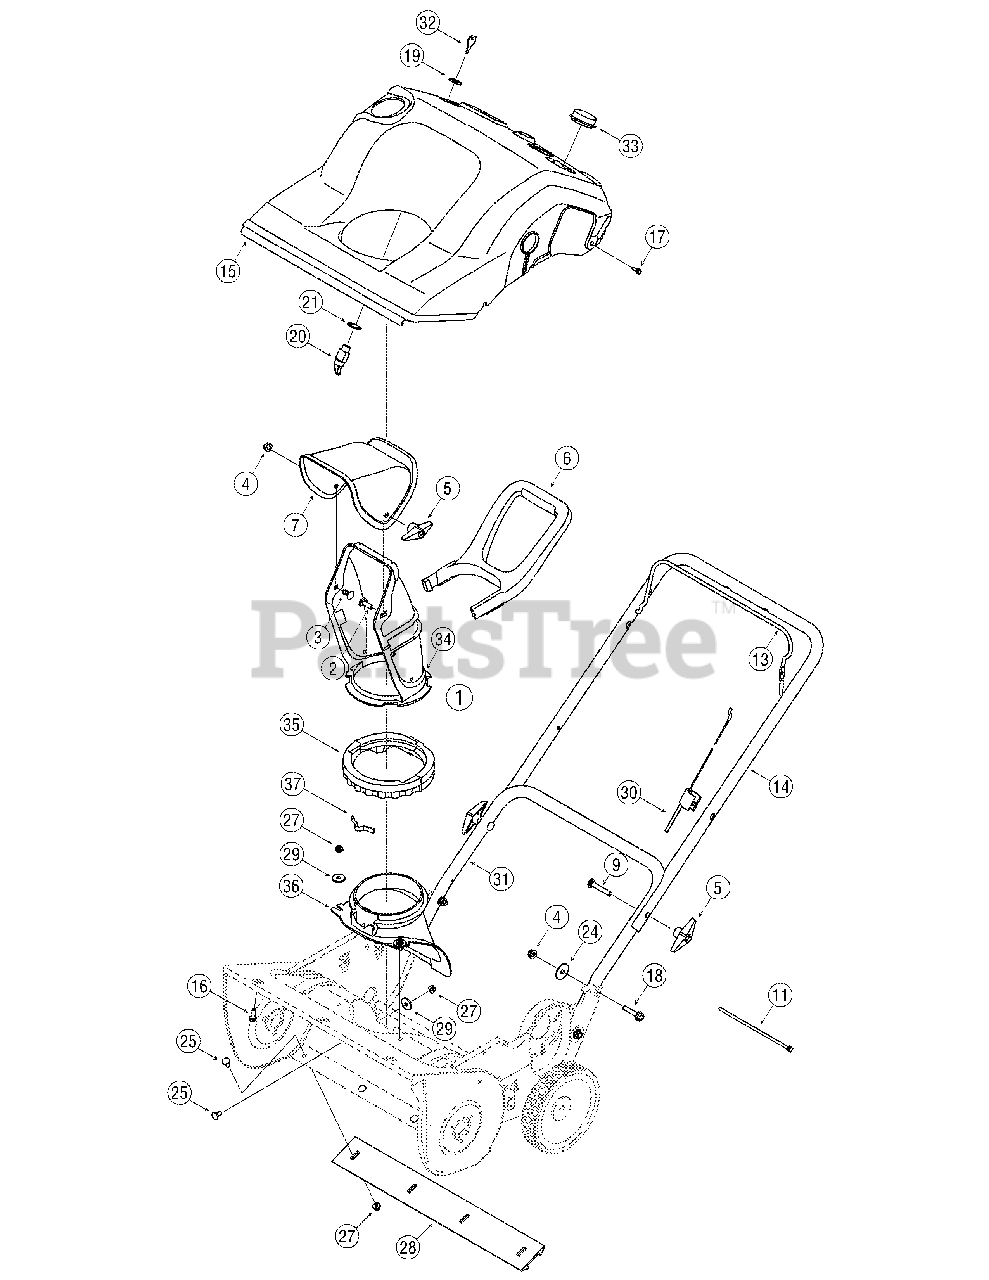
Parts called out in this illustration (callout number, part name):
1	Lower Chute Ass’y (Incl. #5-7 and 10)
2	Carriage Screw 5/16-18 x 1.0
3	Carriage Bolt 5/16-18 x .75
4	Flange Locknut 5/16-18 Gr. F, Nylon
5	Handle Knob Assembly
6	Chute Handle
7	Upper Chute
8	Flat Washer .349 ID x .879 OD x .063
9	Carriage Bolt 5/16-18 x 2.0 Gr. 5
11	Cable Tie
15	Shroud Ass’y (98 cc)
15	Shroud Ass’y (139 cc)
16	Hi-Lo Screw 1/4-15 x .50
17	Hex Wash B-Tapp Scr #10 x .62" Lg.
18	Hex Scr. 5/16-18 x 1.50 Gr. 5
19	Hex Nut 5/8-32 x .12 Special
20	Key Switch-Electric Start
21	L-WasherInternal
22	Flat Washer .218" ID x .62" OD
24	Flat Washer .22 ID x 1.25
25	Carriage Bolt 1/4-20 x .62
27	Hex L-Flanged Nut 1/4-20 Gr. F Nylon
28	Shave Plate
29	Flat Washer .25 ID x .93 OD x .125
30	Control Cable
32	Ignition Key
33	Spark Plug Cover
34	Lower Chute 5" Dia
35	Ring-Lower Chute
36	Chute Adapter 5" Dia
37	Chute Adjustment Spring
